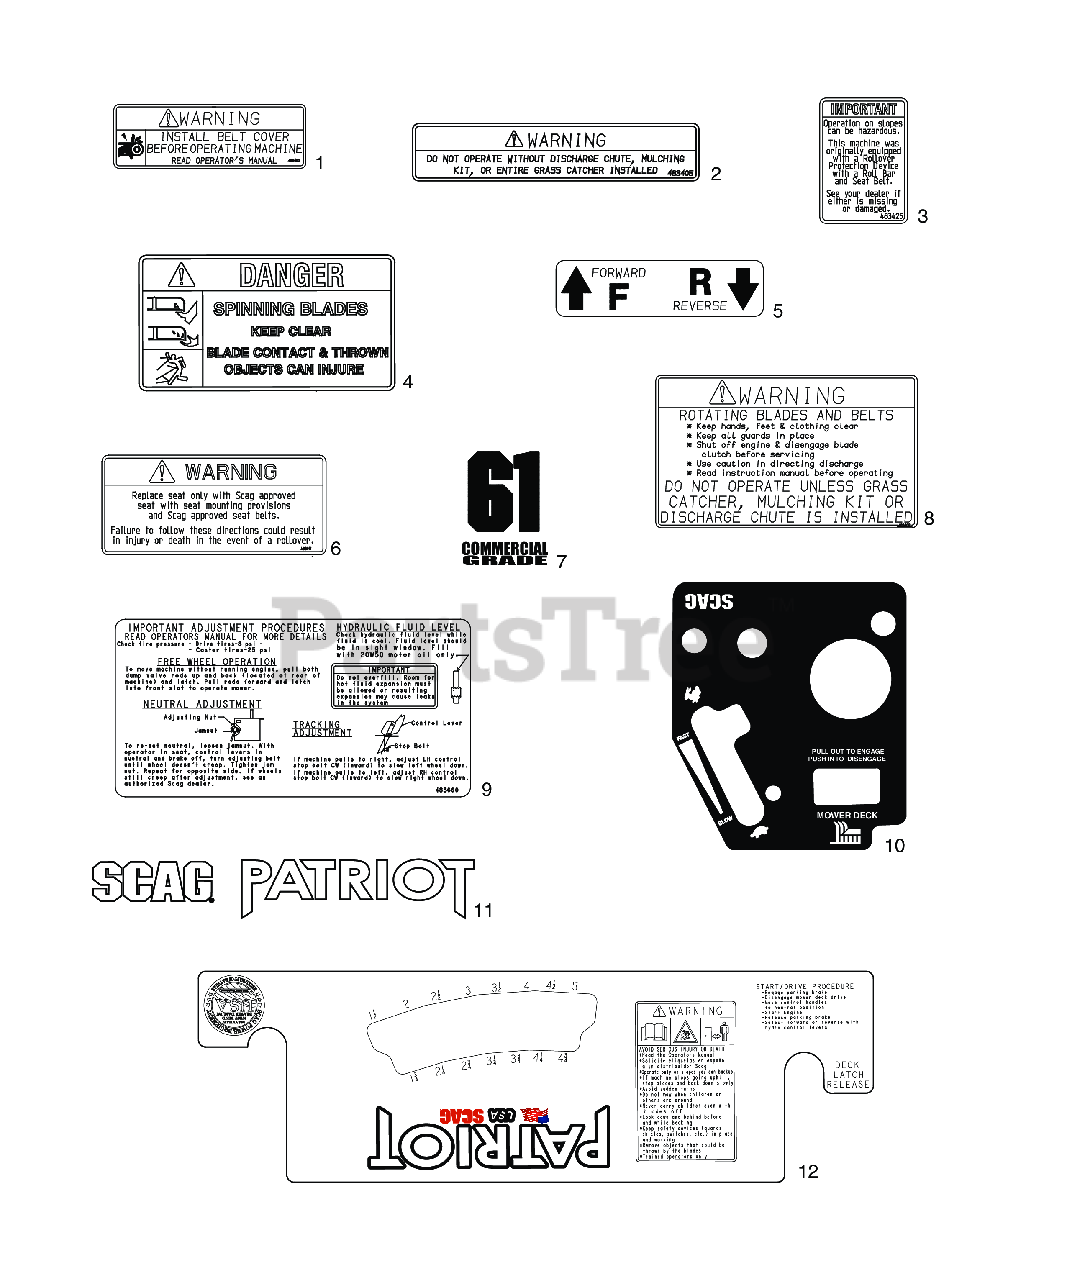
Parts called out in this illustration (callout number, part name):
1	Decal, Warning - Belt Cover
2	Decal, Warning-Discharge
3	Decal, ROPS
4	Decal, Spinning Blades
5	Decal, Traction Control
6	Decal, Seat Replacement
7	Decal, 52 Commercial
8	Decal, Warning - Rotating Blades
9	Decal, Adjustment SFZ
10	Decal, Instrument Panel - SFZ48, SFZ52 & SFZ 61
11	Decal, Front SPZ
12	Decal, Cutting Height - SPZ
